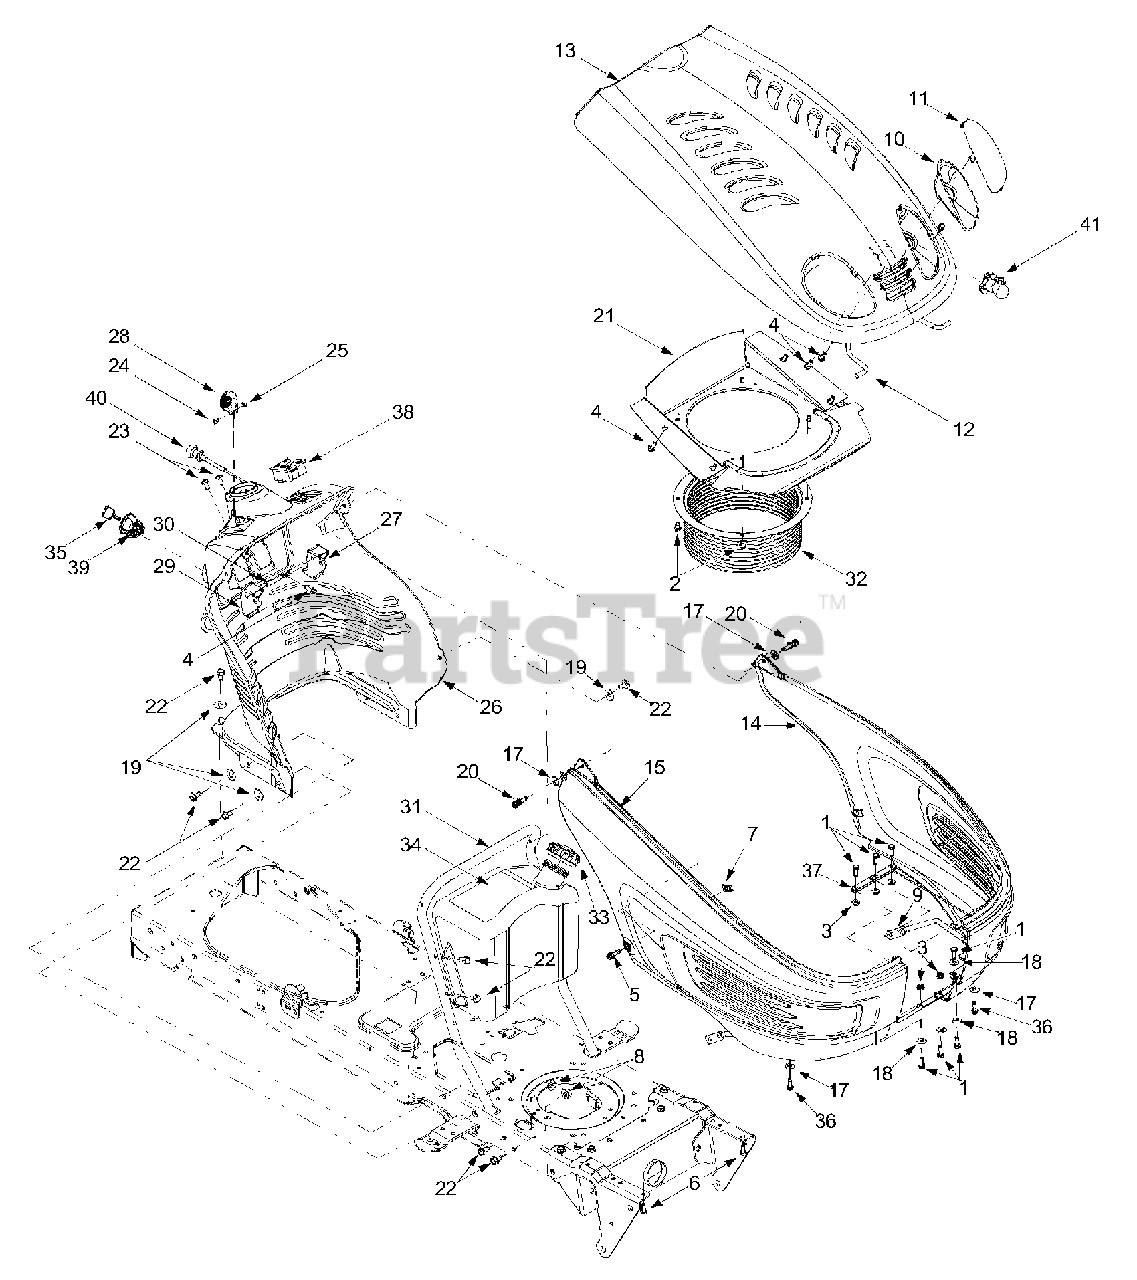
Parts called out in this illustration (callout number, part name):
1	Hex Cap Screw, 1/4-20 x .75
2	Self-tapping Screw, 1/4-20 x .5
3	Hex Flange Lock Nut, 1/4-20
4	Self-tapping Screw, 1/4-15 x .75
5	Pan Phillips Screw, 1/4-20 x .75
6	Hex Cap Screw, 5/16-18 x 1.25
7	U-type Speed Nut, 1/4-20
8	Flange Lock Nut, 5/16-18
11	RH Headlight Lens
12	Hood Support Rod
13	Hood
14	LH Side Panel
15	RH Side Panel
17	Flat Washer, .283 x .75 x .030
18	Flat Washer, .28 x .74 x .063
19	Flat Washer, .349 x 1.0 x .063
20	Self-tapping Screw, 1/4-20 x 1.25
22	Self-tapping Screw, 5/16-18 x .625
23	Torx TTScrew, 1/4-14 x .625
24	Torx Screw, #8-32 x .375
25	Hex Nut, 8-32
26	Dash Panel: 4-style
27	Parking Brake Button
28	Throttle Control Lever
29	Cruise Control Button
30	Brake/Cruise Pivot Rod
33	Fuel Cap
34	Fuel Tank: 2-gallon
35	Ignition Key w/ plastic cover
36	TT Screw 1/4-20 x 0.5
39	Ignition Switch
40	Choke Knob/Cable (Model U604H)
41	Headlight Assembly
